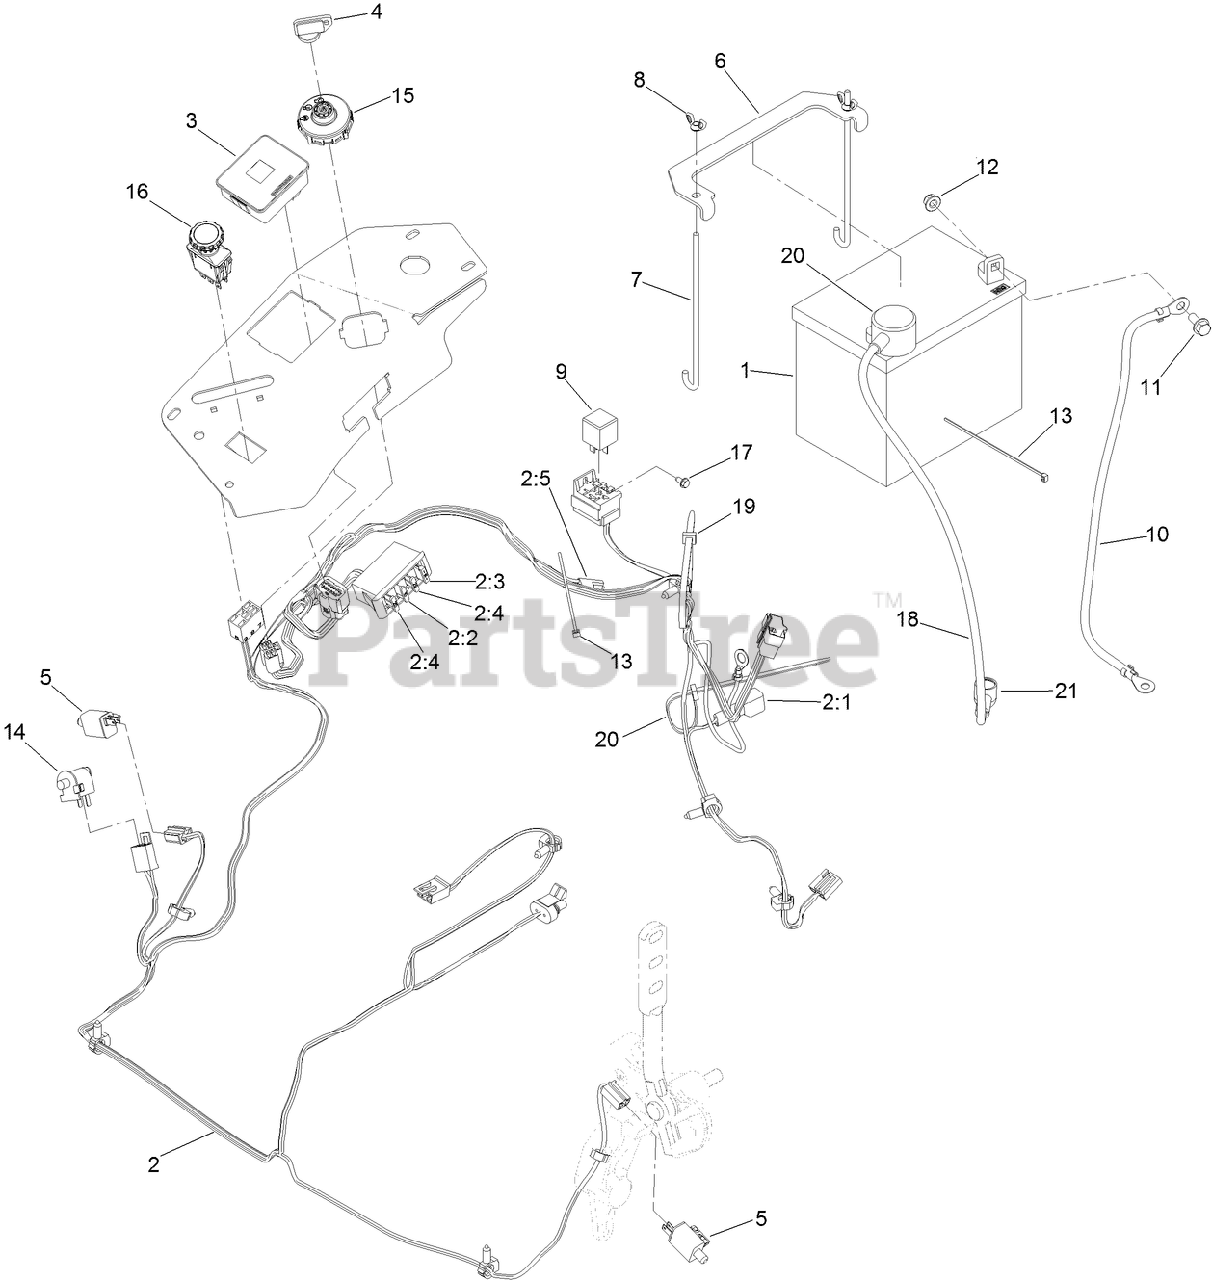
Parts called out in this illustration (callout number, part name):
1	BATTERY-DRY
2	HARNESS-WIRE, MAIN
2:2	FUSE-BLADE, 10 AMP
2:3	FUSE-BLADE, 15 AMP
2:4	FUSE-BLADE, 25 AMP
2:5	CAP-PLUG
3	FUEL/HOUR METER ASM
4	KEYS-IGNITION (SPARE PAIR)
4	KEY-IGNITION
5	SWITCH
6	STRAP-TIE DOWN, BATTERY
7	BOLT-HOLDDOWN
8	WINGNUT
10	CABLE-BATTERY, NEGATIVE
11	SCREW-HH
12	NUT-HF, NI
13	TIE-CABLE
14	SWITCH-BAIL
15	SWITCH-IGNITION
16	SWITCH-PTO, 10 AMP
17	SCREW-HWH
18	CABLE-BATTERY, POSITIVE
19	TIE-PLASTIC
20	INSULATOR-BATTERY
21	INSULATOR-SOLENOID
